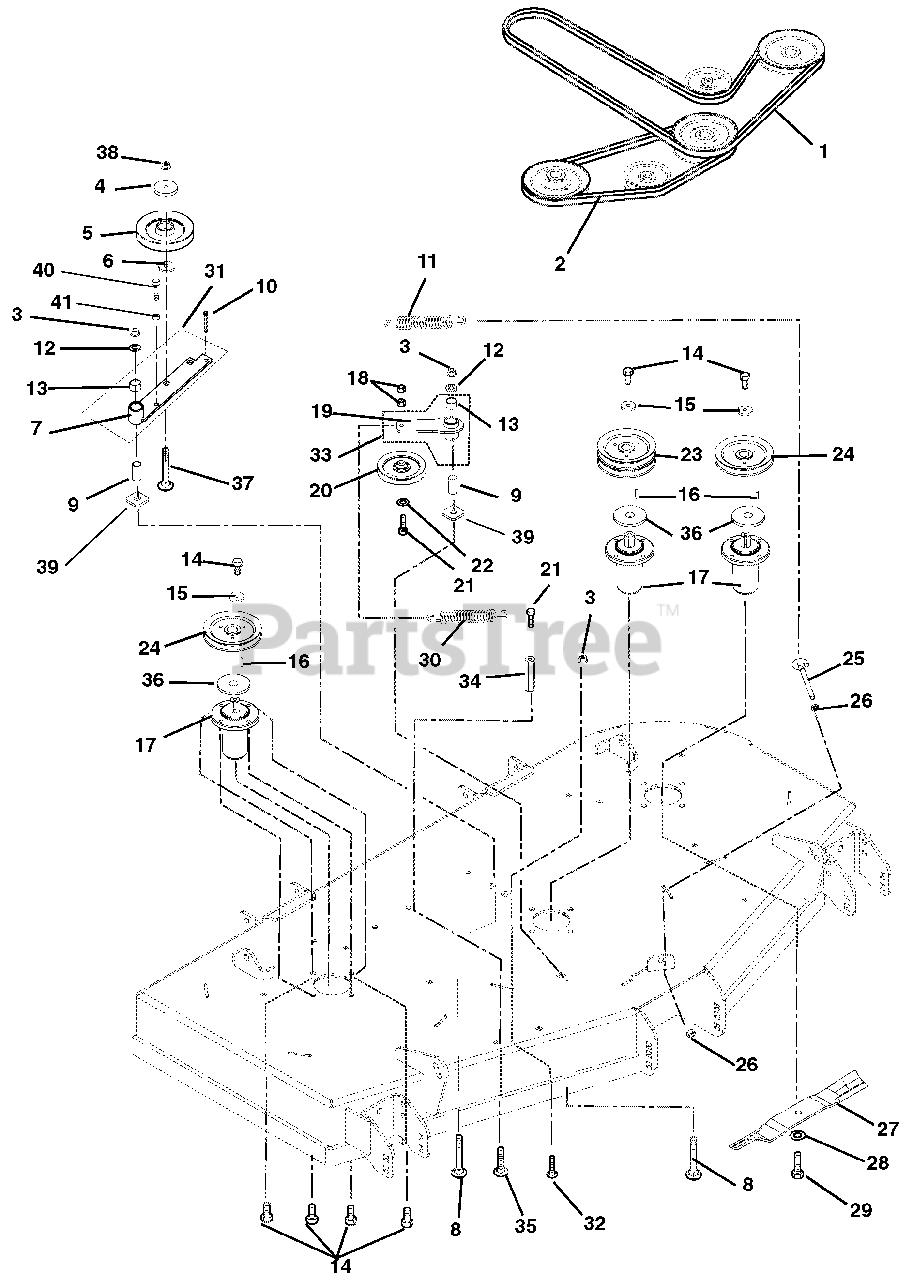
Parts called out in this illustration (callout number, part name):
1	HEX BELT, BB-WRAPPED
2	V-BELT, B-COGGED
3	@NUT-LK-NYL-FLG .50-13 YWZC
4	CAP, IDLER BEARING SEALING
5	PLY-V 6.0 X .500 ID SNGL BRG.
6	BSHG, SPCR .502X.997X.50 PM
7	WMT, IDLER ARM
8	@BLT-RHDSSQNK .50-13X3.50 G5YZ
9	BSHG, SPCR .502X.997X2.03 PM
10	BLT,SHLDR EP .38-16X.30 HEX YZ
11	SPRING, EXTENSION
12	WSHR-FL-STL .531X1.250X.10 YWZ
13	BSHG, 1.00 X 1.125 X 1.937
14	BLT-HEX .38-16X1.0 GR8 YZ EP30
15	WSHR,FLT STL.406X1.50X.245YWZC
16	KEY, SQ .25X.25X1.00 RC 40-50
17	ASSEMBLY, SPINDLE
18	@NUT-LK-CTR .38-16 YWZC
19	WMT, IDLER ARM
20	ASM, V-IDLER 5.00 O.D.
21	@BLT-HEX .38-16X2.25 GR5 YWZC
22	@WSHR-FL-STL.406X.812X.065 YWZ
23	SHEAVE, DOUBLE 1"ID X 6.00"OD
23	SHEAVE, DOUBLE 1"ID X 6.75"OD
23	SHEAVE, DOUBLE 1"ID X 8.25"OD
24	SHEAVE, SINGLE 1"ID X 6.00" OD
24	SHEAVE, SINGLE 1"ID X 6.75"OD
24	SHEAVE, SINGLE 1"ID X 8.25"OD
25	BOLT, .38-16X4.50 .62 DIA EYE
26	NUT-HEX-JAM .375-16 YWZC
27	BLADE, MULCH 18.00"
27	BLADE, MULCHING (20.50")
27	BLADE,MOWER-72"MULCH(24.5"LG)
28	WSHR-BLVL .669X1.535X.138
29	BLT-HEX .62-18X1.75 GR8 YWZC
30	SPRING, EXTENSION
31	ASM, IDLER PIVOT ARM (PTO)
32	BLT-RDHDSHSQNKFT.50-13X1.50 G5
33	ASM, IDLER ARM (DECK)
34	NUT COUPLING .375-16X1.75
35	@BLT-RDHDSHSQNK.38-16X1.0 G5YZ
36	RETAINER, GREASE
37	@BLT-RDHDSQNK .50-13X3.00 G5YZ
38	@NUT-LK-CTR .50-13 YWZC
39	WSHR-FLT .640X1.75X.250
40	@BLT-HEX .38-16X2.75 GR5 YWZC
41	@NUT-HEX .38-16 YWZC
